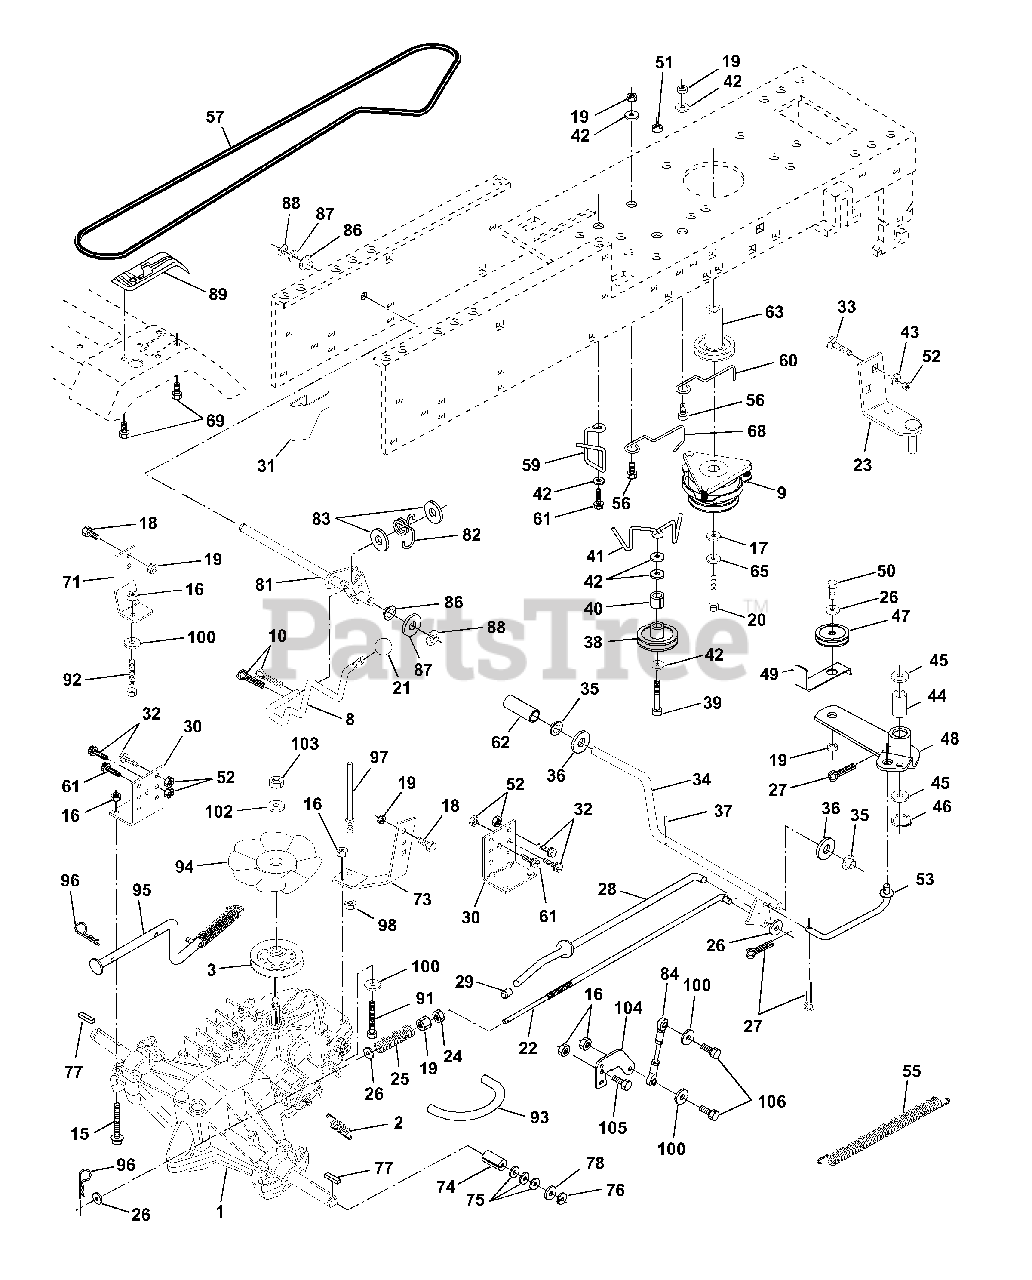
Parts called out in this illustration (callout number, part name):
1	Transaxle w/cas Hydro 310-0650
2	Spring, Return, Brake
3	Pulley, Transaxle Hydro 750 LT
8	Rod Shift Hydro LT
9	Clutch Elecric
10	Pin Cotter 1/8 x 1 CAD
15	Bolt Hex 5/16-18 Unc Flghd
16	Nut Lock Hex W/Ins. 5/16-18 Unc P
17	Washer 1-1/2 OD x 15/32 ID x .250
18	Bolt Fin Hex 3/8-16 Unc x 1 Gr.5
19	Nut Lock Hex W/Ins 3/8-16 Unc
20	Bolt, Hex 7/16-20 x 4-1/4 Ga. 5
21	Knob Deluxe 1/2-13 UNC BLK/BLK
22	Rod, Brake Hydro
23	Bracket Asm Mtg CL
24	Nut Hex Jam 3/8-16 UNC
25	Spring, Brake Rod
26	Washer
27	Pin Cotter 1/8 x 3/4 CAD.
28	Rod, Parking Brake
29	Cap,Parking Brake
30	Bracket, Transaxle
31	Keeper Belt Lh
32	Bolt Hex Hd 5/16-18 Unc x 3/4
33	Bolt Carriage 5/16-18 UNC x 3/4
34	Shaft, Foot Pedal
35	Bearing, Nylon
37	Pin, Roll
38	Pulley, Idler, Flat
40	Spacer Split
41	Keeper, Belt Retainer
42	Washer 13/32 x 13/16 x 12 Ga
43	Washer 11/32 x 5/8 x 12 Ga.
44	Bearing, Nylon
45	Washer, Hardened
46	Ring, Klip
47	Pulley, Idler, V-Groove Plastic
48	Bellcrank Assembly
49	Retainer, Belt Style Spring
50	Bolt
52	Nut Crown Lock 5/16-18
53	Link, Clutch
55	Spring, Return, Clutch
56	Bolt, Fin Hex 3/8-16 UNC x 1 1/4
57	V-Belt, Ground Drive
59	Keeper, Center Span
60	Keeper Belt Engine
61	Screw Thdrol. 3/8-16 x 3/4 Ty. TT
62	Cover, Pedal Premium
63	Pulley, Engine
65	Washer Lock Hvy HLCL Spr 7/16
68	Keeper Belt Engine
71	Strap Torque Lh Hydro 18/20" T
73	Strap Torque Rh Hydro 18/20" T
74	Spacer, Split
75	Washer 25/32 x 1-1/4 x 16 Ga.
77	Key, Square
78	Washer 25/32 x 1-5/8 x 16 Ga
81	Shaft Asm. Cross Hydro 20" Tires
82	Spring Torsion T/A
83	Washer 17/32 x 3/4 x 16 Ga.
84	Rod, Tie Hydro 20" Tires SPH Ball 4.75
86	Bushing Rod Strig. 629/632 ID
87	Washer 21/32 x 1-1/4 x 16 Ga.
88	Ring Klip #5304-62
89	Console, Hydro YT/GT Fender
91	Bolt Fin Hex 5/16-18 x 2-1/4
92	Bolt Fin Hex 5/16-18 Unc x 1-1/2
93	Line Fuel Hydro 4"
94	Fan, Hydro 7"
95	Control Asm. Bypass Hydro
96	Retainer Spring 1" Zinc/Cad
97	Keeper Belt Rh Hydro 0750.18/20"
98	Nut Keps Hex 3/8-16 Unc
100	Washer 11/32 x 3/4 x 16 Ga.
102	Washer Belleville .501D x 1.50D
103	Nut Hex Jam Toplock 1/4-20 Unf
104	Arm, Control Hydro
105	Screw Cap Hex 5/16 x 18 x 1
106	Bolt Fin Hex 5/16-18 Unc x 1-1/4
